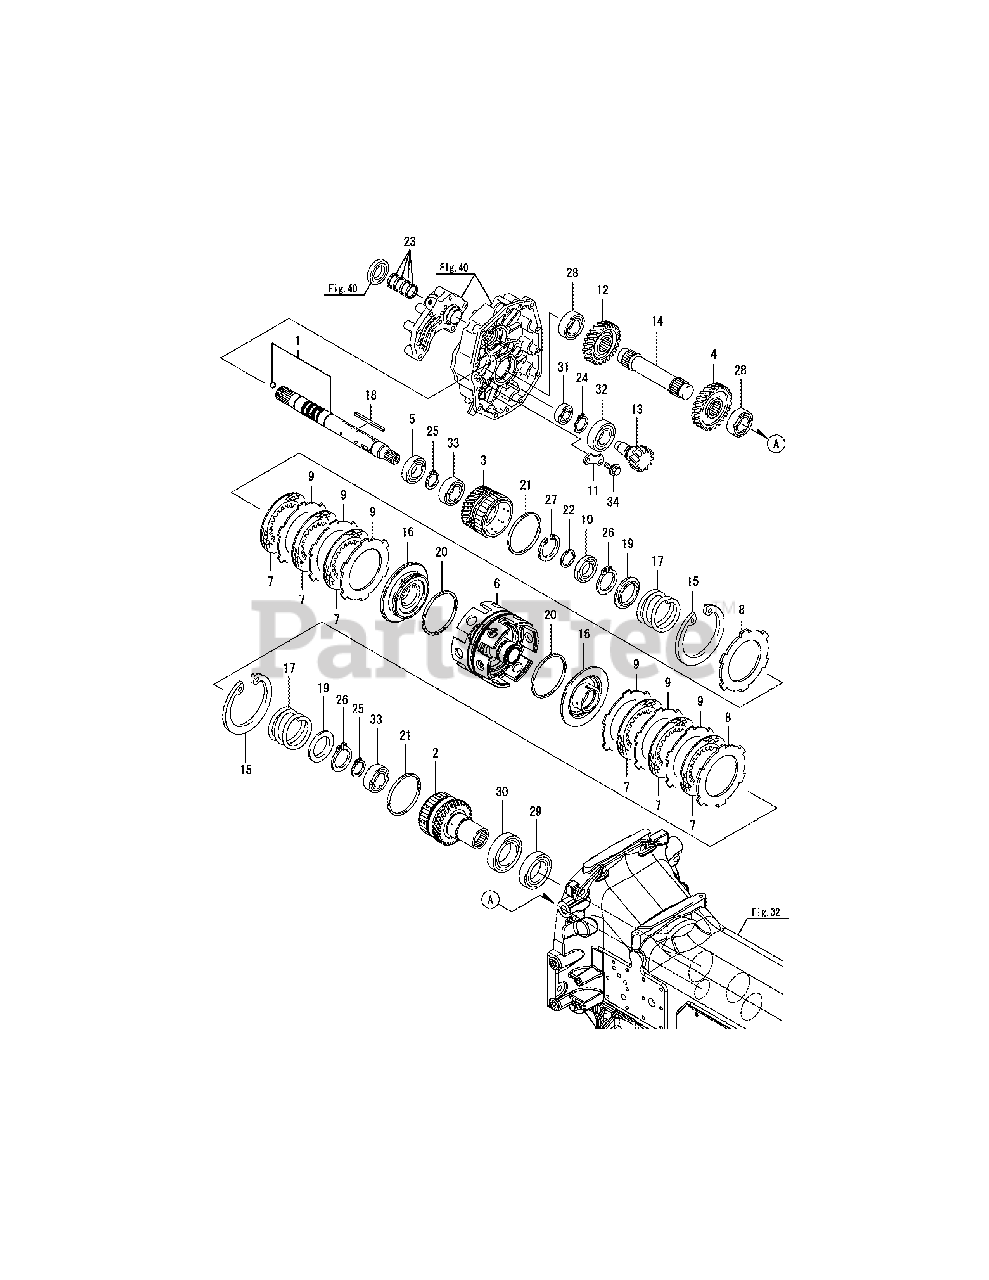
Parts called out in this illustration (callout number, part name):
1	SHAFT ASSY, INPUT
2	GEAR,CLUTCH 36
3	GEAR,CLUTCH 33
4	GEAR 37F, DRIVEN
5	BEARING TMB006
6	CYLINDER, CLUTCH
7	DISC, CLUTCH 130
8	PLATE, STEEL 5.0
9	PLATE, STEEL 3.0
12	GEAR 34, DRIVEN
14	SHAFT, DRIVEN P/R
16	PISTON, CLUTCH
17	SPRING, RETURN
23	RING 262730073, SEAL
34	BOLT M 8X 16 PLATED
